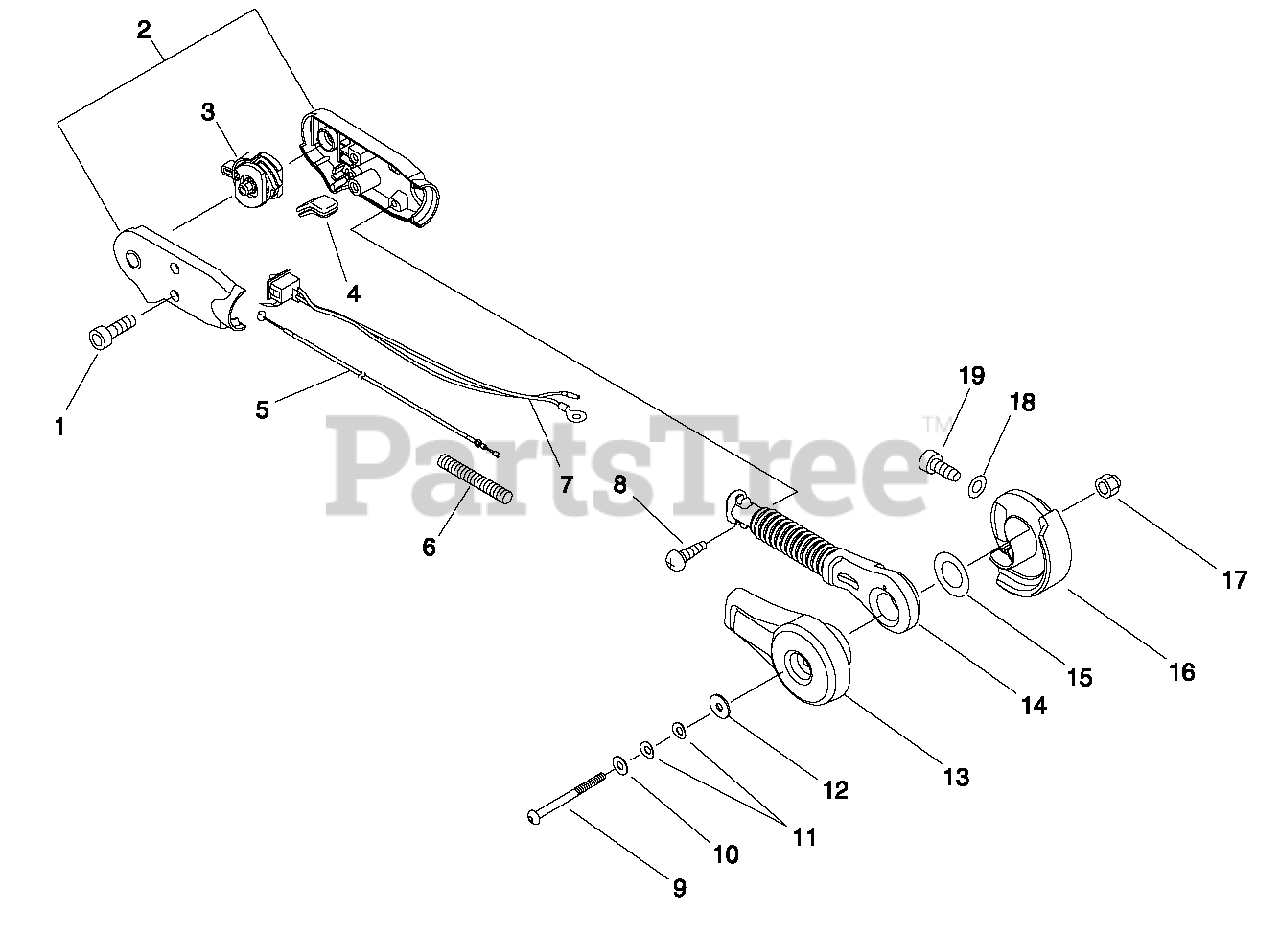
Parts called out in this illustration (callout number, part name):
1	SCREW - 5X14
2	CONTROL HANDLE KIT
3	THROTTLE CONTROL ASSY
5	CABLE, THROTTLE
6	TUBE, PROTECTIVE - CORRUGATED
7	SWITCH, IGNITION
8	SCREW - 5X20
9	BOLT - 6
10	WASHER - 6
11	WASHER - SPRING
12	WASHER - 6
13	BRACKET, ARM - OUTER
14	ARM, THROTTLE CONTROL
16	BRACKET, ARM - INNER
17	LOCKNUT - 6
18	WASHER - 5
19	SCREW - 5X25 -- TAPPING
